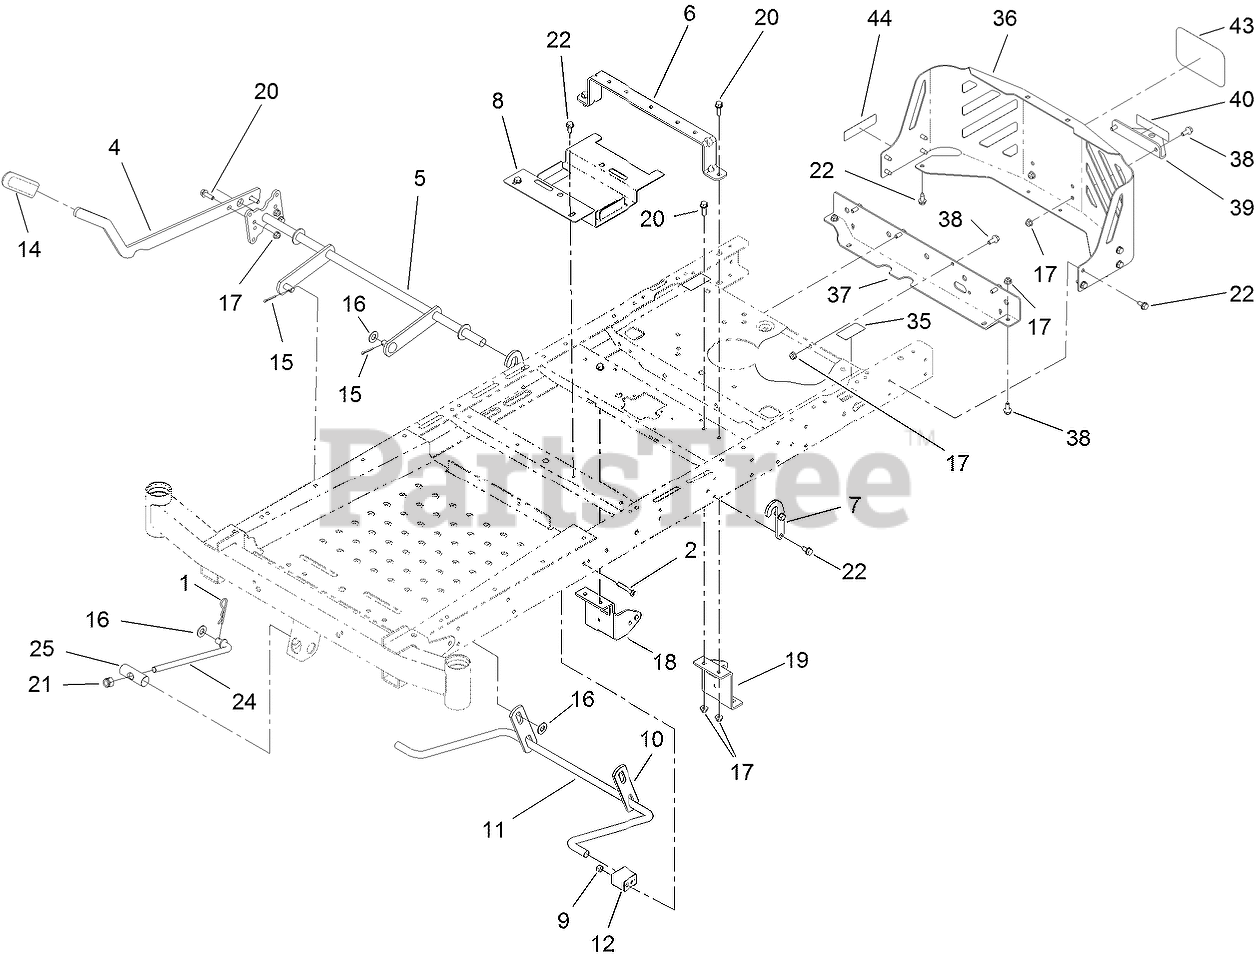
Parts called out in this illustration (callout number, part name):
1	PIN-COTTER
2	SCREW-HSBH
4	LEVER-LIFT
5	LIFT-DECK, WIDE
6	BRACE-SEAT, REAR
7	BRACKET-LIFT
8	BRACKET-BATTERY
9	NUT-LOCK, NI
10	LINK-LIFT
11	ARM-LIFT, REAR (WIDE)
12	BLOCK-PIVOT
14	GRIP-LEVER
15	PIN-COTTER
16	WASHER-FLAT
17	NUT-HF, NI
18	MOUNT-HYDRO, FRONT (RH)
19	MOUNT-HYDRO, FRONT (LH)
20	SCREW-HHF
21	NUT-HEX
22	SCREW-HWHTF
24	ROD-MOUNT, DECK
25	PIN-PIVOT
35	DECAL-BYPASS
36	GUARD-ENGINE, WIDE
37	CROSSMEMBER-REAR, WIDE
38	SCREW-HHF
39	BRACKET-HITCH
43	DECAL
44	DECAL-ARRESTER, SPARK
